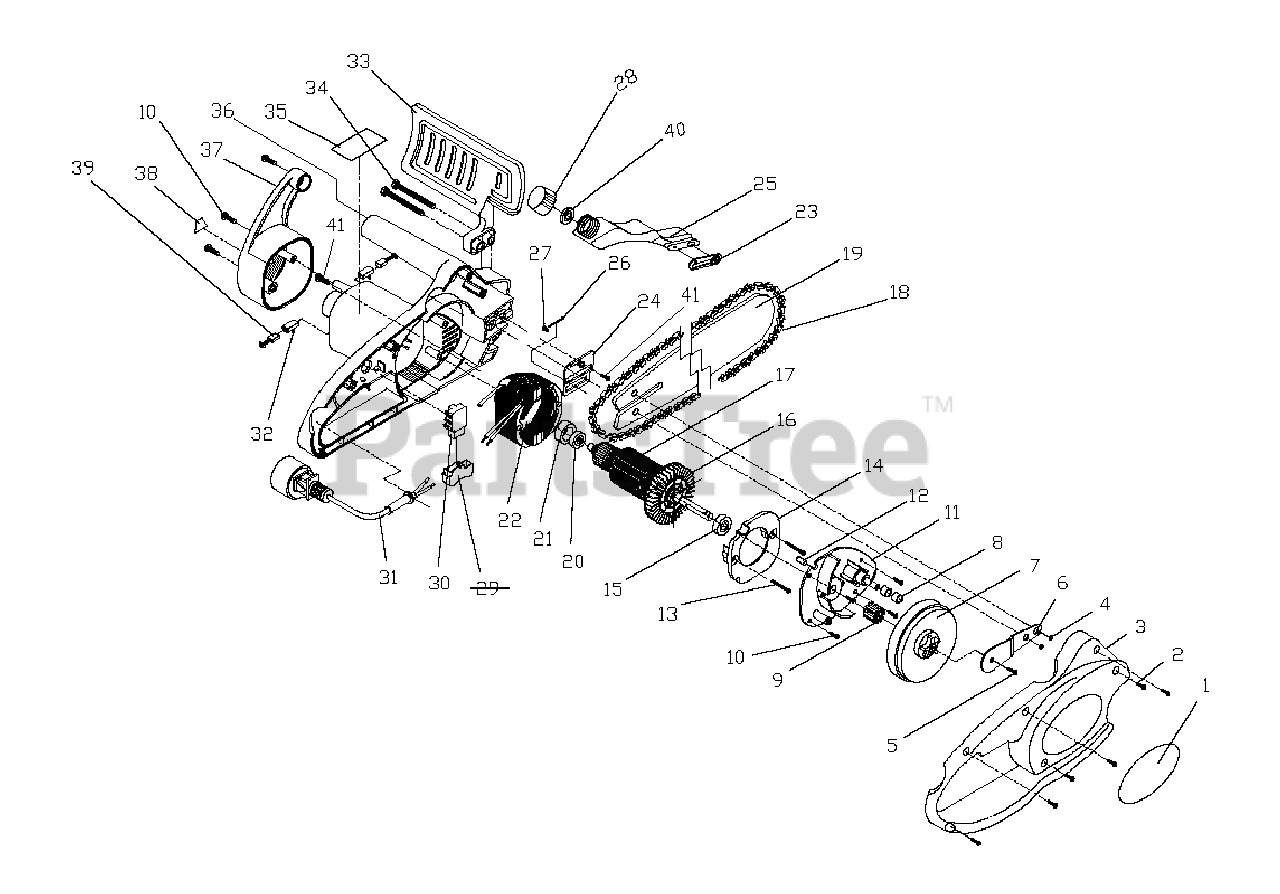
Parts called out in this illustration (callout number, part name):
5	FIXED SCREW
6	SPROCKET SUPPORT
7	SPROCKET-GEAR
8	ROLLER BEARING
9	MOTOR GEAR
11	MOTOR COVER ASSEMBLY
12	RUNNER STICK
14	WIND GUIDE
17	ARMATURE ASS'Y
18	14" CHAIN
21	ANTI-VIBRATILLAGE PAD
22	FIELD ASS'Y
23	ANTI-SPILLAGE PAD
24	ADJUSTING PLATE
26	REGULATION SCREW
30	LOCK-OFF SWITCH
31	POWER CORD
33	FRONT-HAND GUARD
35	WARNING TAG
37	REAR COVER
39	BRUCH HOLDER
40	ANTI SPILLAGE
